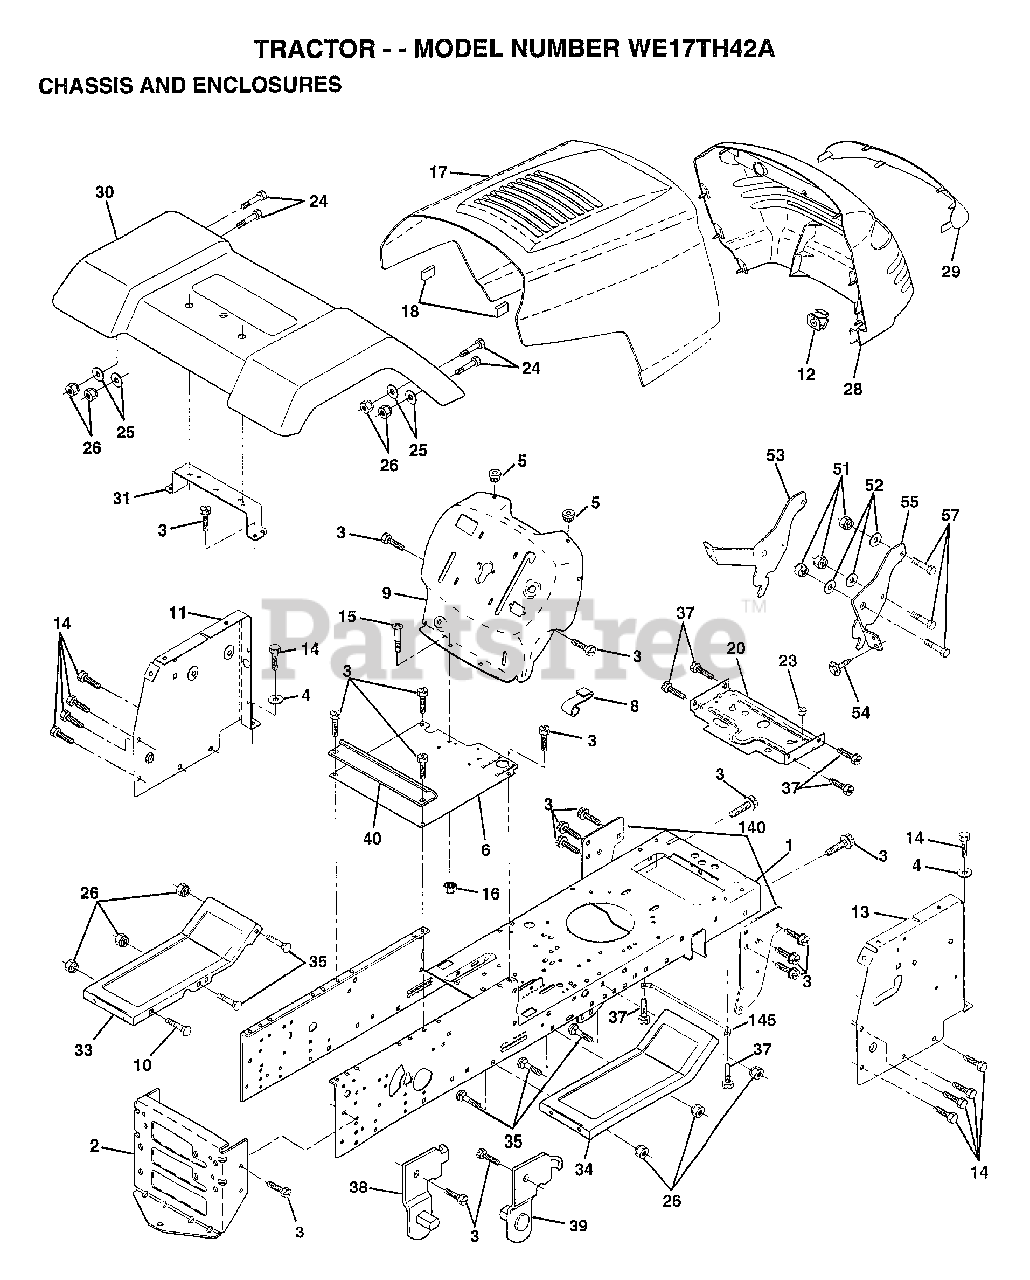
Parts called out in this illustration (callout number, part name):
1	CHASSIS.STAMPING
3	SCREW
4	WASHER
5	BUMPER-HOOD/DASH
6	SADDLE
8	CLIP.RETAINER
9	DASH SILKSCREEN
11	"PANEL-DASH,LH"
12	CLIP.TINNERMAN
13	PANEL.ASM.SLKSCR.DASH.RH
14	SCREW LT
15	SCREW
17	HOOD.STEEL.ASSY
20	"PLATE-MTG,BATT/FU"
24	BOLT
25	WASHER
26	NUT
28	GRILLE-MS428
29	LENS.GRILLE.PRIVATE LABEL
30	FENDER.LTST.WLDMNT.W.SHIFT
31	BRACKET SUPT FEND
33	FOOTREST.LH.LT/GT
34	FOOTREST.RH.LT/GT
35	BOLT
37	SCREW LT
38	BRACKET ASM LH
39	BRACKET ASM RH
40	SPACER FENDER LT
51	NUT
52	WASHER
53	BRACKET.GRILLE.LH
54	SCREW.HEX.WS.HD
55	BRACKET.GRILLE.RH
140	BRKT SUSPENSION
145	"ROD POVOT,CHASSIS"
